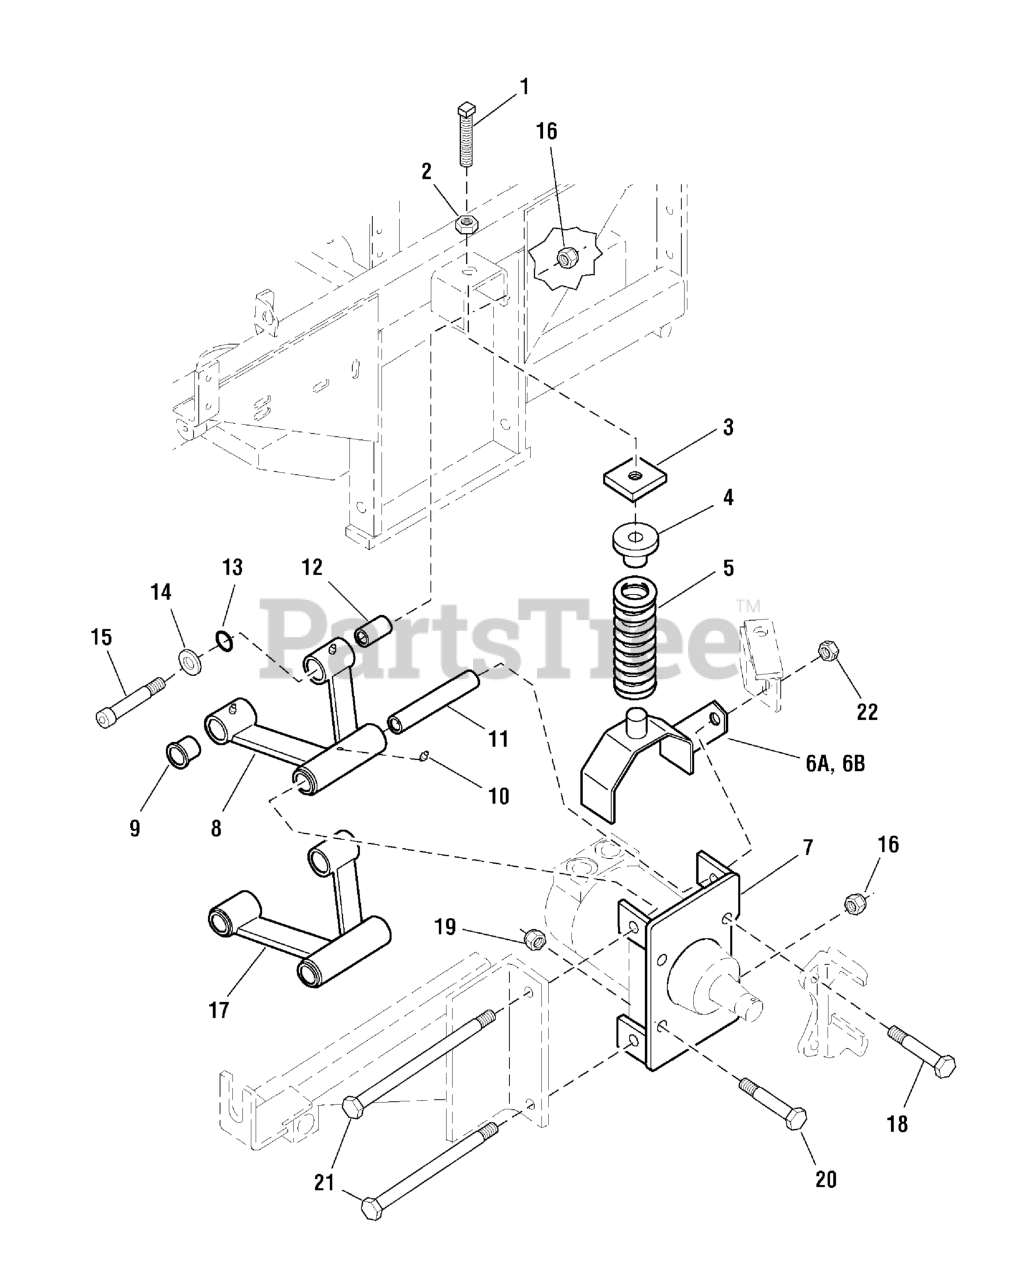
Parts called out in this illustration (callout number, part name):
1	SET SCREW, Square Head, 1/2-13 x 3
2	NUT, 1/2-13 Hex Jam
3	SPRING COMPRESSION PLATE
4	SPRING RETAINER
5	SPRING, SUSPENSION
6A	SPRING SADDLE-LH
7	WHEEL MOTOR MOUNT
8	ASSM, UPPER A-ARM - RED
9	BUSHING, Flange
10	GREASE FITTING
11	PIVOT SLEEVE, Long
12	PIVOT SLEEVE, Short
13	O-RING
14	WASHER, A-Arm
15	BOLT, Allen Head, 1/2-13 x 3
16	NUT, 1/2-13 HEX NYLON LOCK
17	LOWER A-ARM ASSEMBLY
18	BOLT, 1/2-20 x 3
19	NUT, Hex, Nylon Lock, 1/2-20
20	BOLT, 1/2-20 X 2-1/2" GD5 CZ
21	BOLT, 1/2-13 x 6-1/2
22	NUT, 1/2-13 Hex Side Lock
